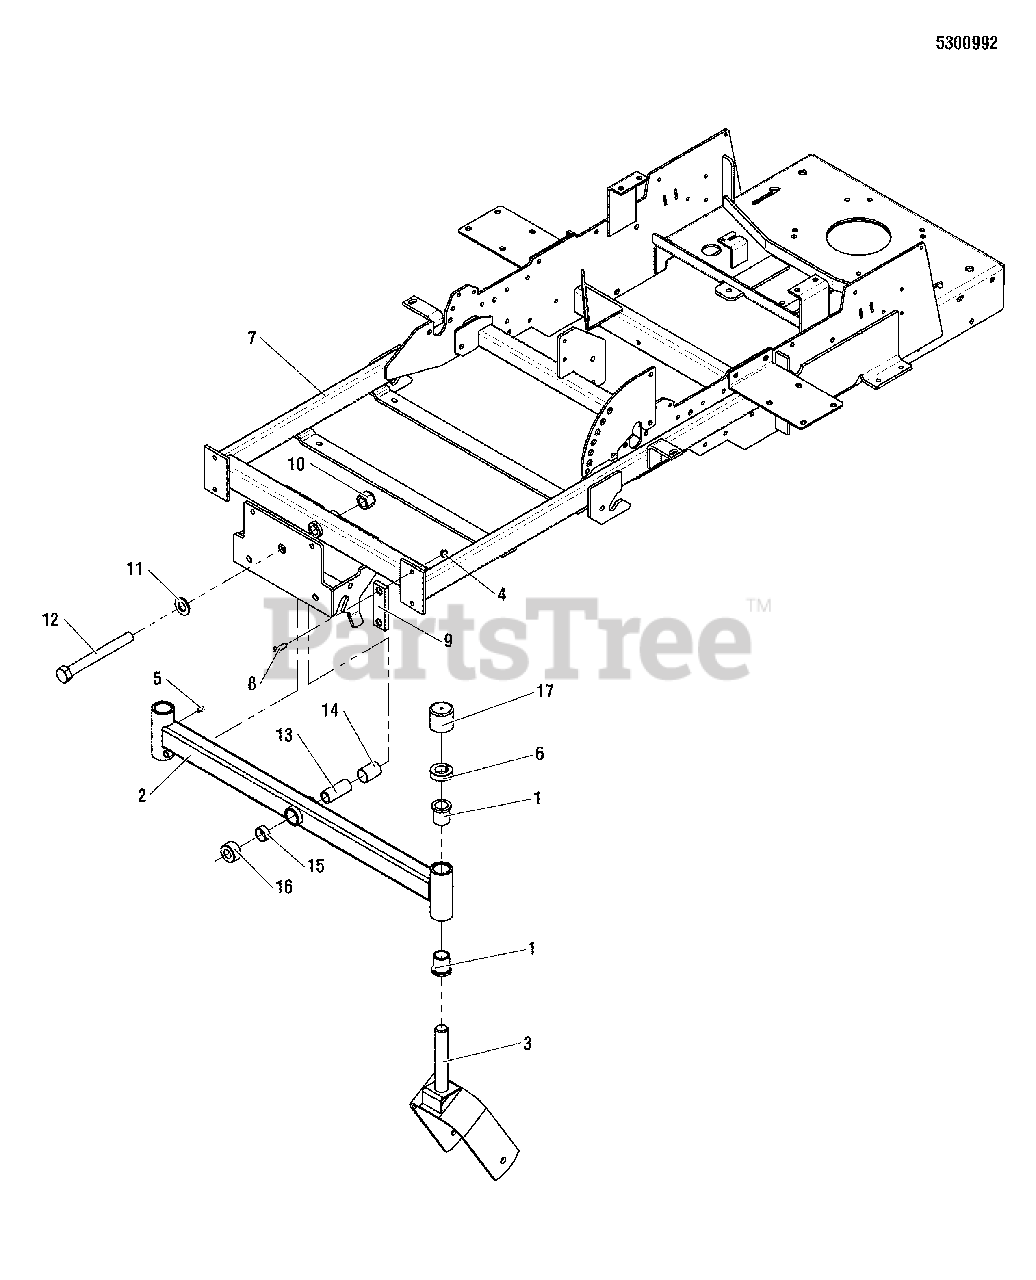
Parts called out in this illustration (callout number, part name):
1	BUSHING, FLANGE
2	WELD, PIVOTING FRONT END
3	WELD,CASTER YOKE
4	NUT, 5/16-18 HEX NYLON LOCK
5	GREASE FITTING, 1/4-28 STRAIGHT
6	COLLAR, 1" SPLIT
7	WELD, MAINFRAME, SNAPPER ZT - RED
8	SCREW, 5/16-18 X 1 FLAT HD SC
9	PAD, FRICTION, .375 X 1.25 X 4.00
10	NUT, 3/4-16 HEX NYLON LOCK
11	WASHER, 3/4" SAE
12	BOLT, 3/4-16 X 7" YZ GD5
13	SPACER, .75 X 1.00 X 2.38
14	PIVOT BEARING, 1.00" X 1.125" OD X 1.50"
15	PIVOT BEARING, 1.00 X 1.125 OD X .50
16	SPACER, .76X 1.50 X .79
17	CAP, VINYL 1.687 X 1-1/2
